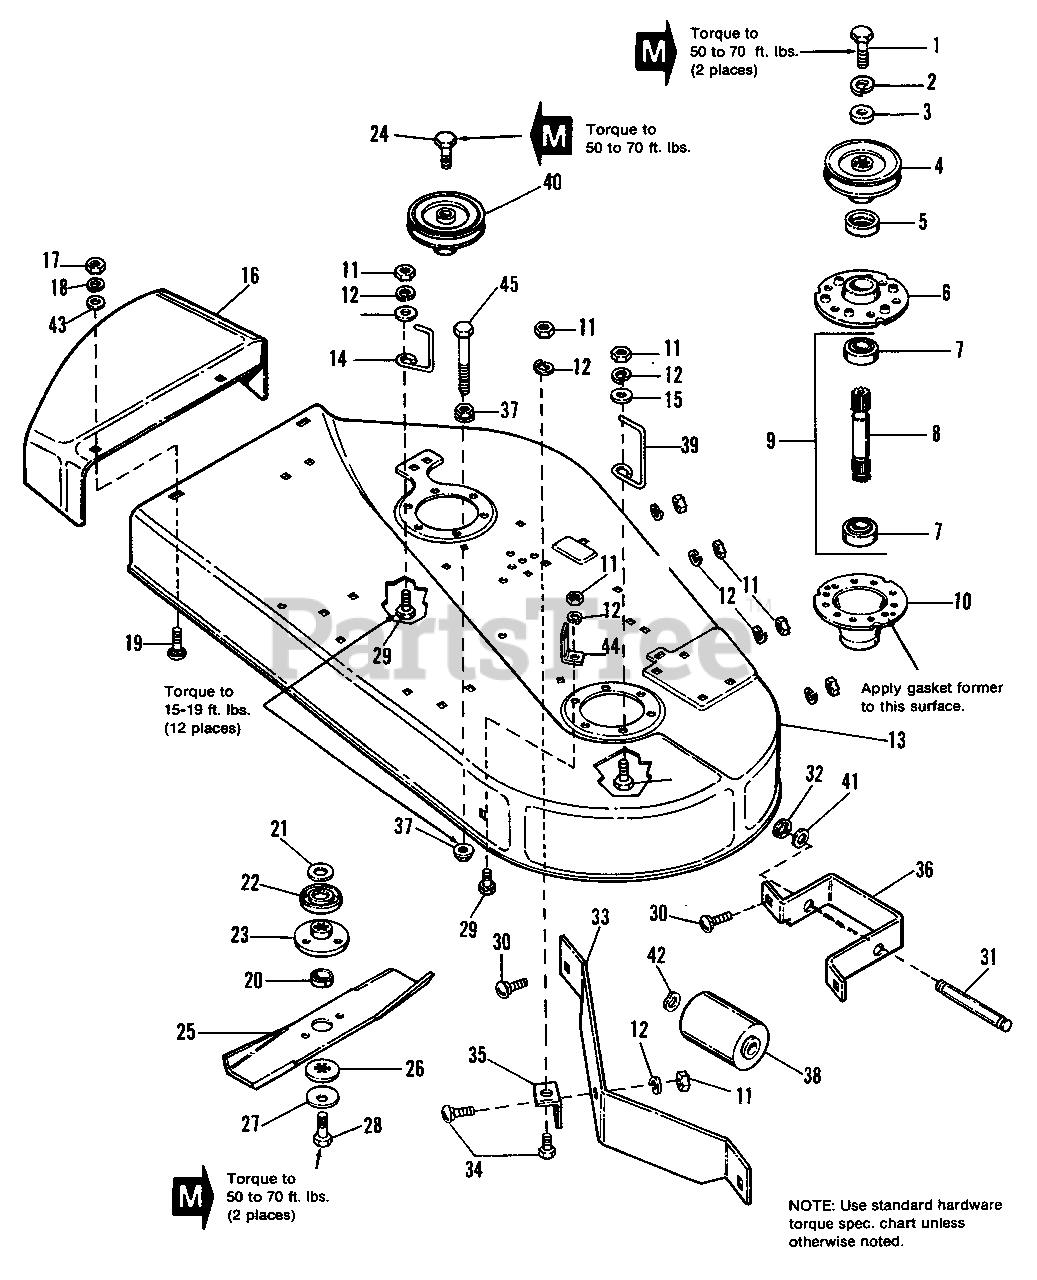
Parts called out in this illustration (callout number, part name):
1	CAPSCREW, Hex Hd., 7/16-14 x 3-1/2
2	LOCKWASHER, 7/16
3	WASHER, 29/64 x 1-1/4 x 1/4
4	PULLEY ASSY.
5	SHIELD, Bearing Upper, Arbor
6	HOUSING, Top
8	SHAFT, Arbor (Incl. Ref. No. 20)
9	SHAFT & BEARING ASSY. (Incl. Ref. Nos. 7, 8, 20)
10	HOUSING, Bottom
11	NUT, Hex, Full, 5/16-18
12	LOCKWASHER, 5/16
13	HOUSING, 36" (Incl. Safety Decals)
15	WASHER, 5/16
16	DEFLECTOR, Mower (1690838)
16	DEFLECTOR, Mower (1691419)
17	NUT, Hex, Full, 3/8-16
18	LOCKWASHER, 3/8
19	BOLT, Carriage, 3/8-16 x 3/4
20	COLLAR, Arbor
21	WASHER, Shim
22	SHIELD, Grass
23	ADAPTOR, Blade
24	CAPSCREW, Hex Hd., 7/16-14 x 2-3/4
26	WASHER, Spline
27	WASHER, Cup
28	CAPSCREW, Hex Hd., 7/16-14 x 1
29	SCREW, Hex, Wash. Hd., Taptite, 5/16-18 x 1
30	BOLT, Carriage, 5/16-18 x 3/4
31	SHAFT, Roller, Center
32	E-RING
33	BAFFLE
34	CAPSCREW, Hex Hd., 5/16-18 x 3/4
35	BRACKET, Mower
36	BRACKET, Center, Roller
37	NUT, Hex Flange Whizlock, 5/16-18
40	PULLEY ASSY.
41	WASHER, Nylon
42	WASHER, Wave
43	WASHER, Plain, 3/8
44	BRACKET, Lift
45	CAPSCREW, Hex Hd., 5/16-18 x 3-1/2
